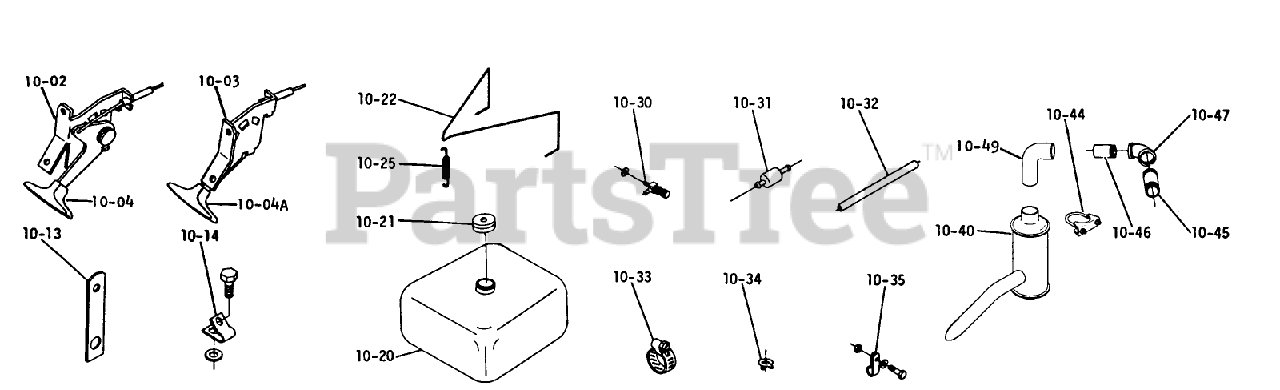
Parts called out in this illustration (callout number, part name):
10-02	Choke Control
10-03	THROTTLE CONTROL
10-03	SCREW
10-03	#10-24 Kep-Nut
10-04	KNOB-CHOKE
10-04A	KNOB-THROTTLE
10-13	Strap
10-13	Washer
10-13	Screw-10-24 X 3/8
10-13	Nut-10-24
10-14	THROTTLE CONTROL CLP
10-14	Clip
10-14	Bolt 1/4-20 x 3/8
10-14	Special Nut
10-14	Bolt, 1/4-20 x 1/2
10-14	Nut-Nylok
10-14	CLIP-CABLE
10-20	Tank-Fuel
10-21	Cap
10-22	HOLD DOWN WIRE
10-25	CLUTCH SPRING
10-30	S/A FUEL VALVE
10-30	SPACER
10-31	Filter
10-32	Fuel Hose
10-32	FUEL HOSE 24" OF 6554
10-32	Hose-Fuel-Pump to Carb 5.5
10-32	Hose
10-32	Skid Bracket
10-32	Hose-Fuel-Pump to Carb. 3"
10-33	CLAMP
10-34	Clamp
10-35	CLAMP-HOSE
10-35	Bolt 5/16-18 x
10-35	Washer
10-35	Nut-Nylok
10-35	Bolt 5/16-18 x 1
10-40	MUFFLER
10-44	ASSY-MUFFLER CLAMP
10-45	Nipple 1" x 1 1/2
10-46	Nipple-Special
10-47	Elbow 90 X 1
10-49	MUFFLER INLET TUBE
